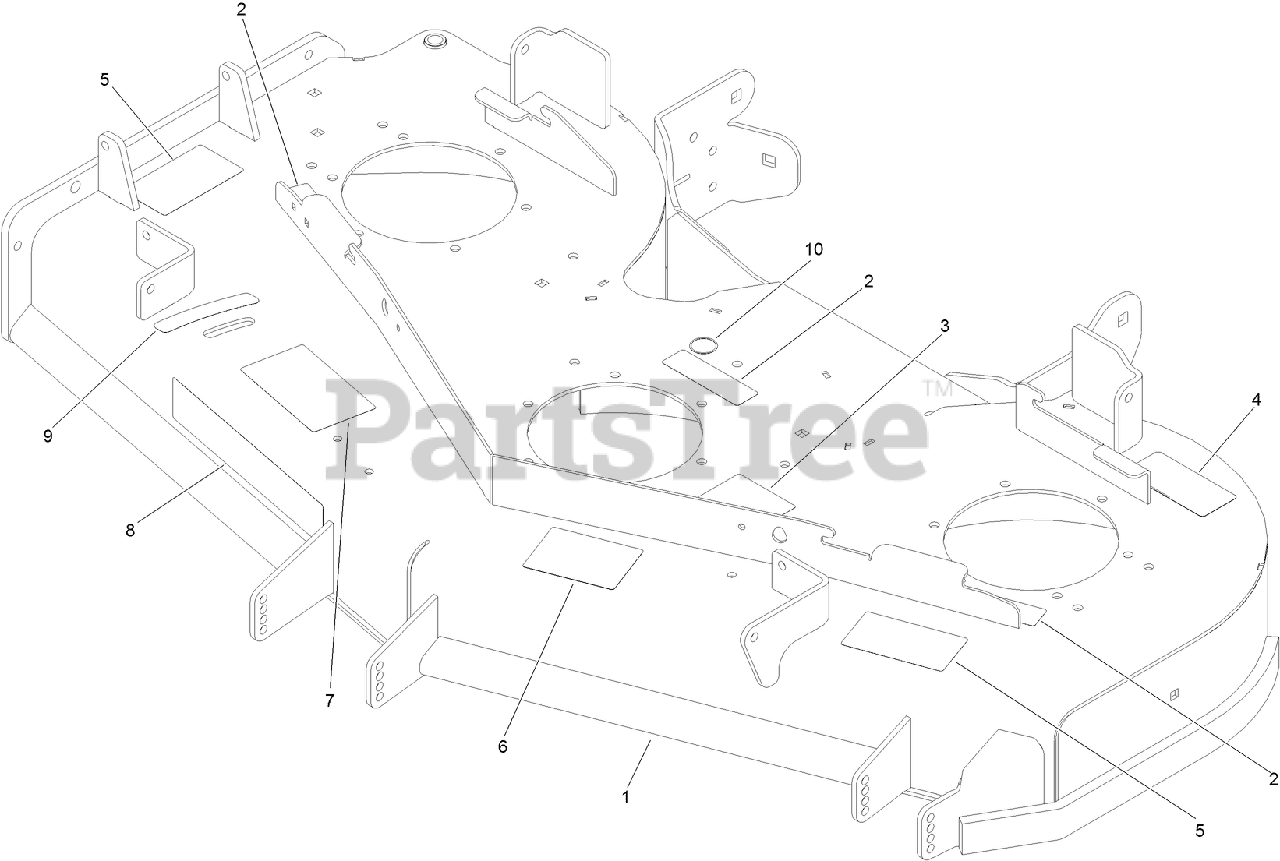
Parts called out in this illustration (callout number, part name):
1	DECK ASM
2	DECAL-COVER, MISSING
3	DECAL-ROUTING, DECK BELT
4	DECAL-TORQUE, BLADE BOLT
5	DECAL-DANGER
6	DECAL-SCALP, ANTI
7	DECAL-ADJUSTMENT, BAFFLE
9	DECAL-SETTING, BAFFLE
10	DECAL-GREASE
